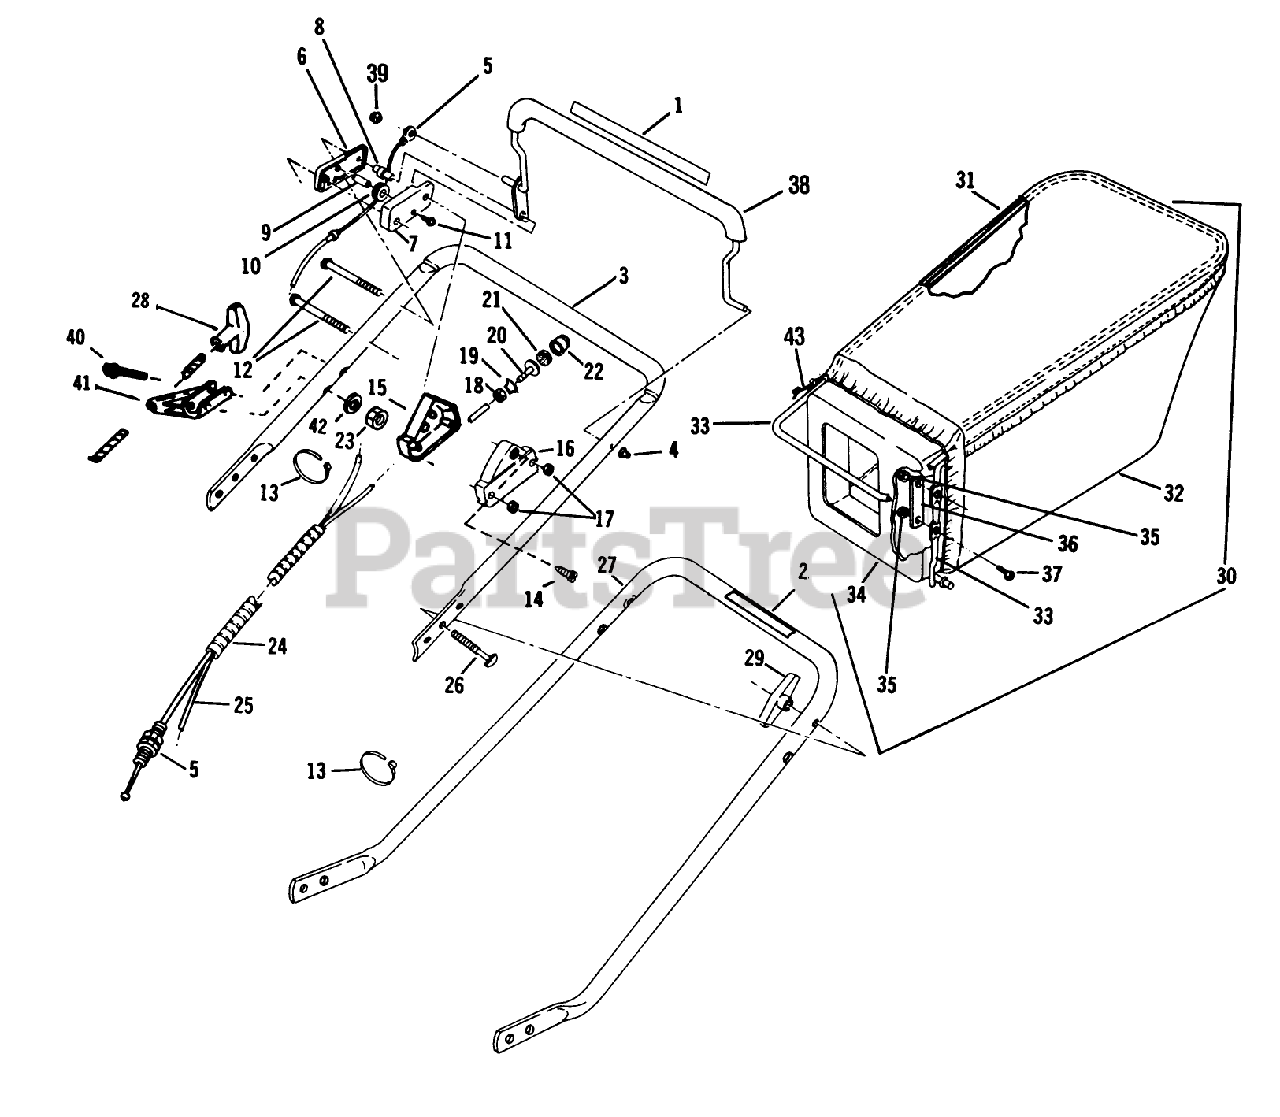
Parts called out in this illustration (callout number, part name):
5	CONTROL CABLE AY
8	COLUMN
9	PIN SKF
11	SCREW
14	SCREW LAWRENCE
17	NUT C/LOCK E
18	LOCKNUT S
21	FILTER S
23	LOCKNUT E
27	HANDLE AY-LOWER (12)
28	HANDLE,STARTER
29	NUT-WING
31	HANGER BAG TROX
34	BAG ADAPTOR PL
35	LOCKNUT E
39	NUT ACORN
42	WASHER
